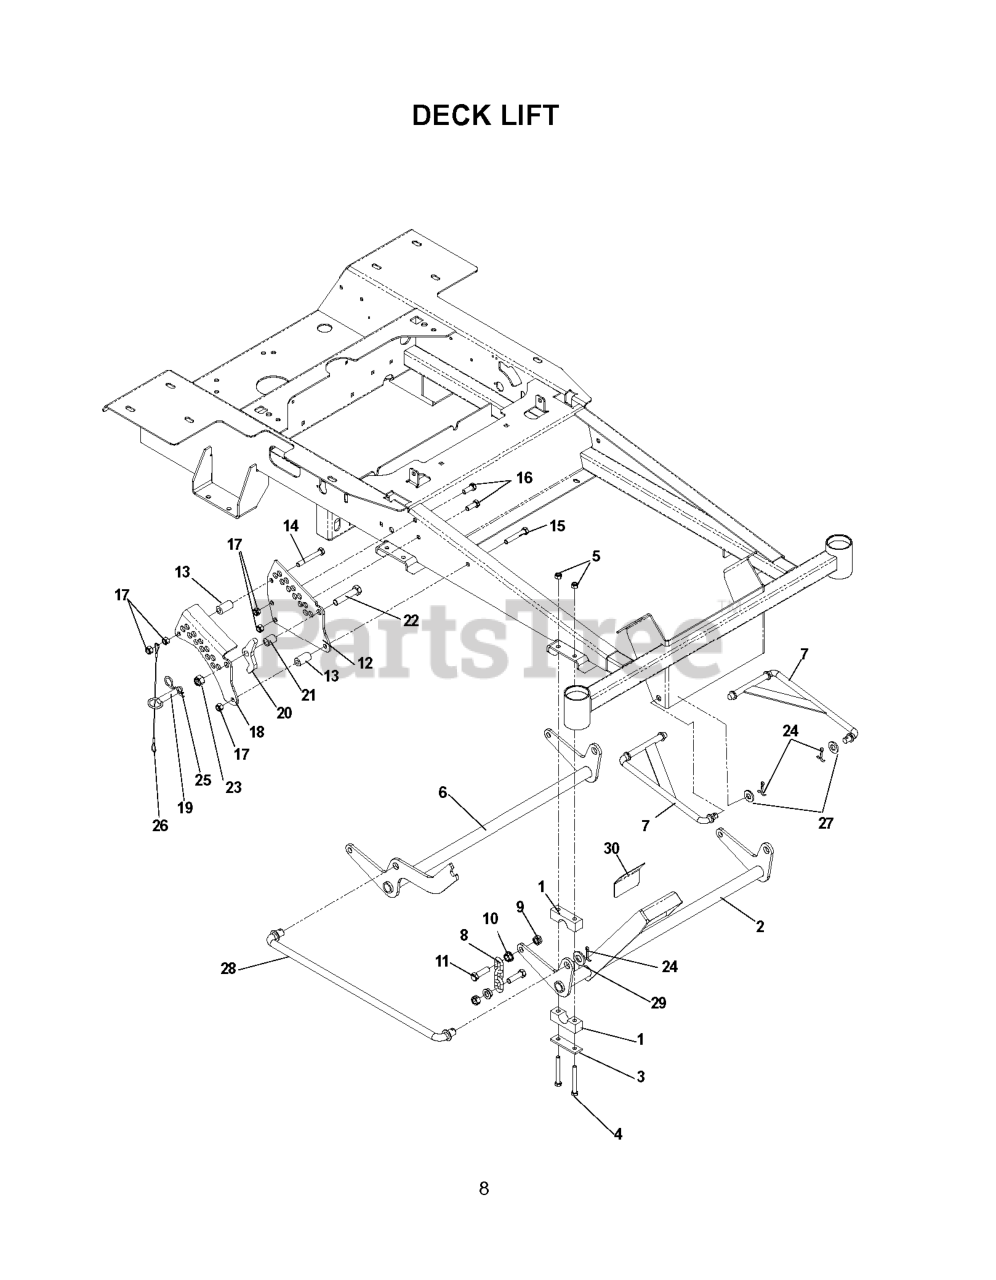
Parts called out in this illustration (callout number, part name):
1	PILLOW BLOCK
2	FRONT LIFT SHAFT
3	REINFORCEMENT BAR
4	HCS 5/16C X 2-3/4
5	NUT 5/16 NYLOC
6	LIFT SHAFT, REAR
7	STRUT LINKAGE
8	LIFT CHAIN - 3 LINK
9	NUT 7/16C CENTERLOCK
10	NUT 7/16C WHIZ
11	HCS 7/16C X 1 1/2
12	HEIGHT ADUST PLATE
13	DECK LIFT SPACER
14	SCREW 3/8C X 2 3/4 HEX CAP
15	HCS 3/8C X 2 1/4
16	HCS 3/8-16X1.GRD.5.ZD
17	NUT 3/8-16 NYLOC
18	HEIGHT ADJUST PLATE, OUTER
20	PAWL, STOP
22	HEX SCREW 1/2-13 X 2.5" GR 5
23	NUT 1/2-13 HEX NYLOC ZD
24	COTTER PIN
25	HAIRPIN #4
27	WASHER 1/2" FLAT
28	CROSS LINK
29	WASHER 5/8 FLAT
30	ANTI-SKID PAD
